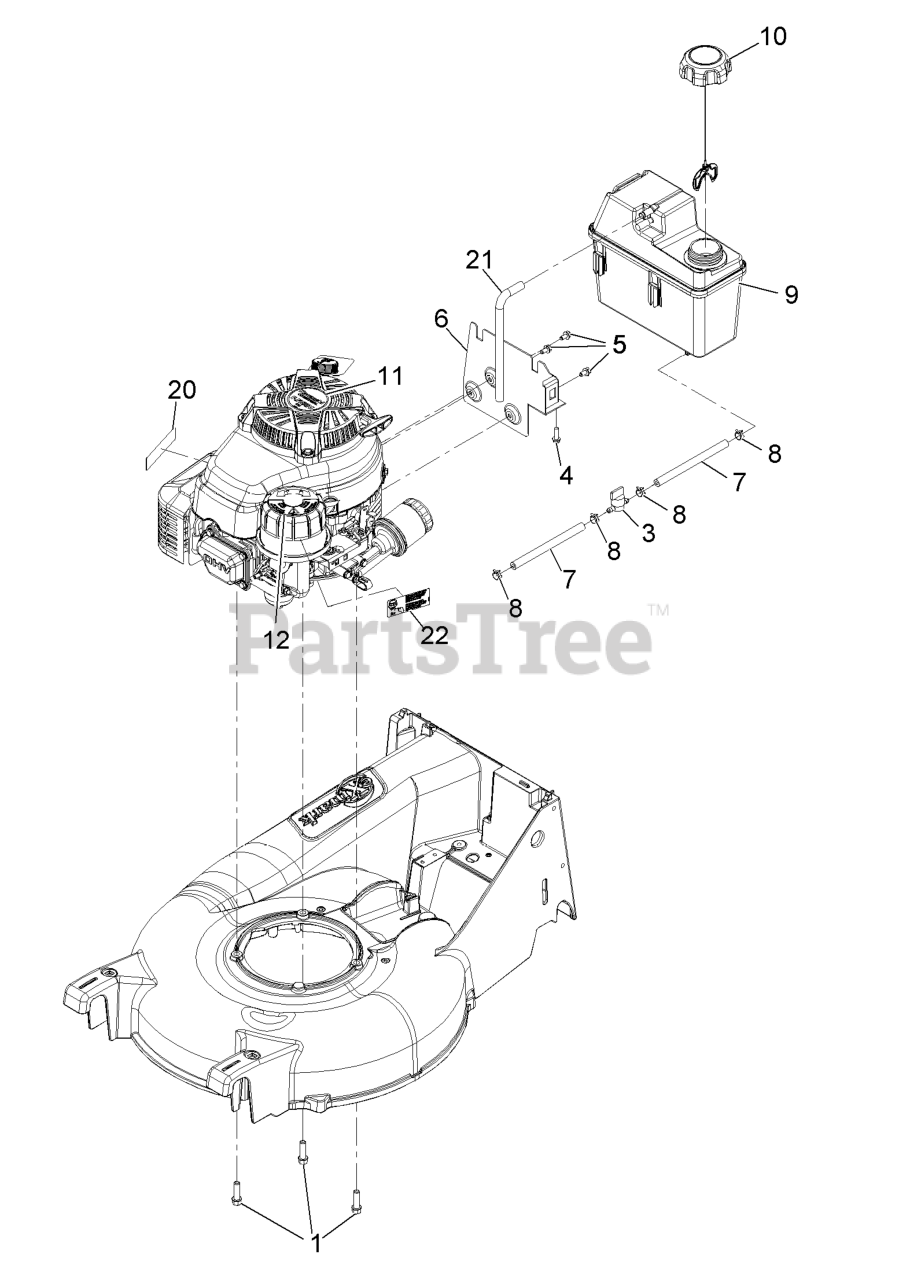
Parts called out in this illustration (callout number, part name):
1	SCREW-TAPTITE
3	VALVE-FUEL
4	SCREW-HWH
5	SCREW-HWH
6	BRACKET,FUEL TANK
7	HOSE-FUEL
8	CLAMP-HOSE
9	TANK-FUEL
20	DECAL-ARRESTER, SPARK
21	HOSE-VENT, CANISTER
22	DECAL, PRIMER
